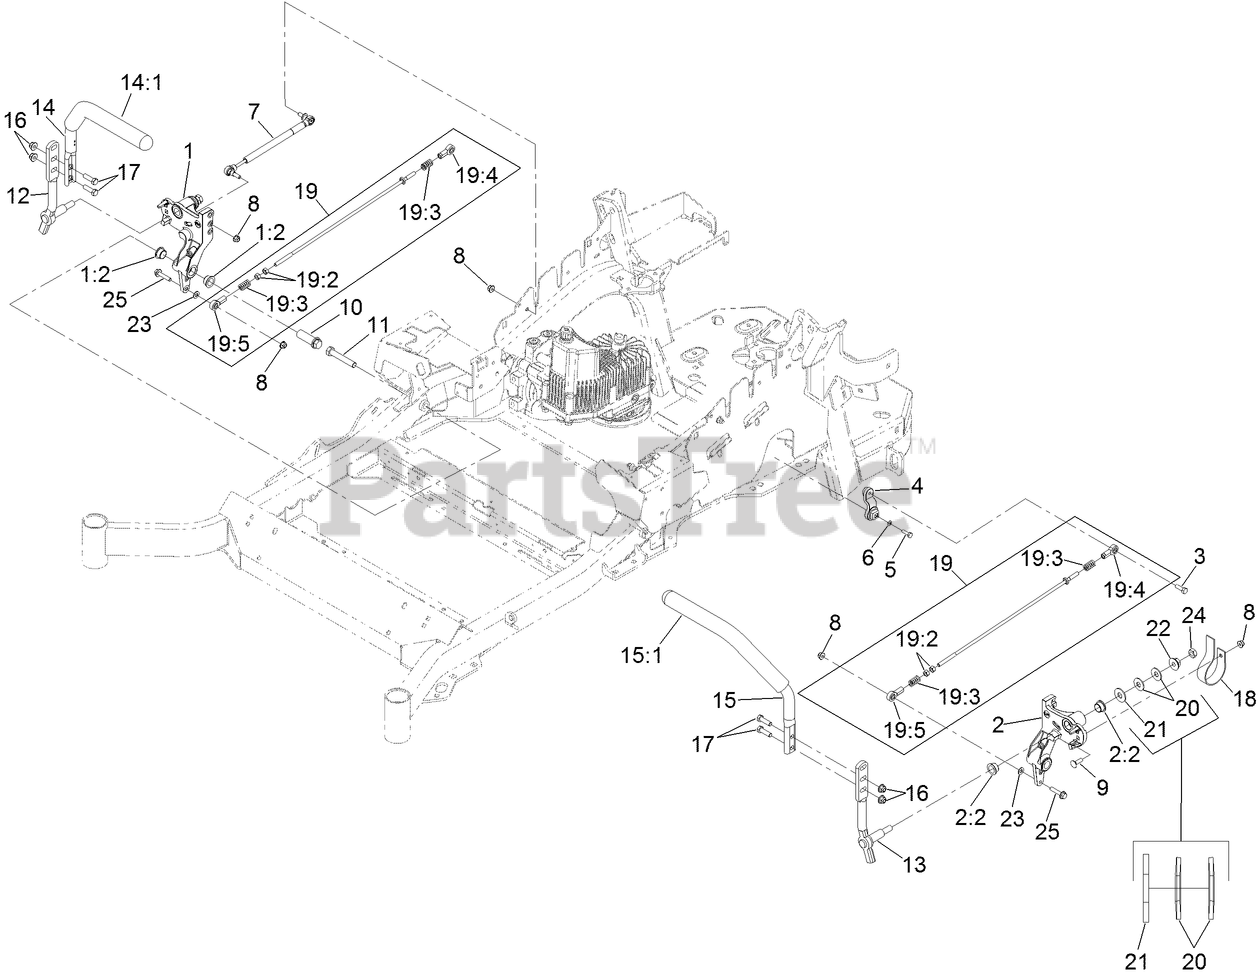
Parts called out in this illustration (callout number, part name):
1	RH MOTION CONTROL AND BUSHING ASM
1:2	BUSHING-FLANGE
2	LH MOTION CONTROL AND BUSHING ASM
2:2	BUSHING-FLANGE
3	SCREW-HH, THREAD LOCKING
4	ARM-CONTROL, PUMP
5	SCREW-HH
6	WASHER-SPRING
7	DAMPER-CONTROL, MOTION
8	NUT-HF, NI
9	BOLT-CARR
10	HUB-THREADED
11	SCREW-HH
12	LEVER-CONTROL MOTION, RH
13	LEVER-CONTROL MOTION, LH
14	RH STEERING HANDLE ASM
14:1	GRIP-CONTROL, LEVER
15	LH STEERING HANDLE ASM
15:1	GRIP-CONTROL, LEVER
16	NUT-HF, NI
17	SCREW-HH
18	SPRING-LEAF
19	PUMP LINKAGE REAR ASM
19:2	NUT-HEX
19:3	SPRING-COMPRESSION
19:4	BALLJOINT-LH
19:5	BALLJOINT-RH
20	WASHER-SPRING
21	WASHER-FLAT
22	NUT-HF
23	WASHER-PLAIN
24	NUT-JAM
25	SCREW-HHF
